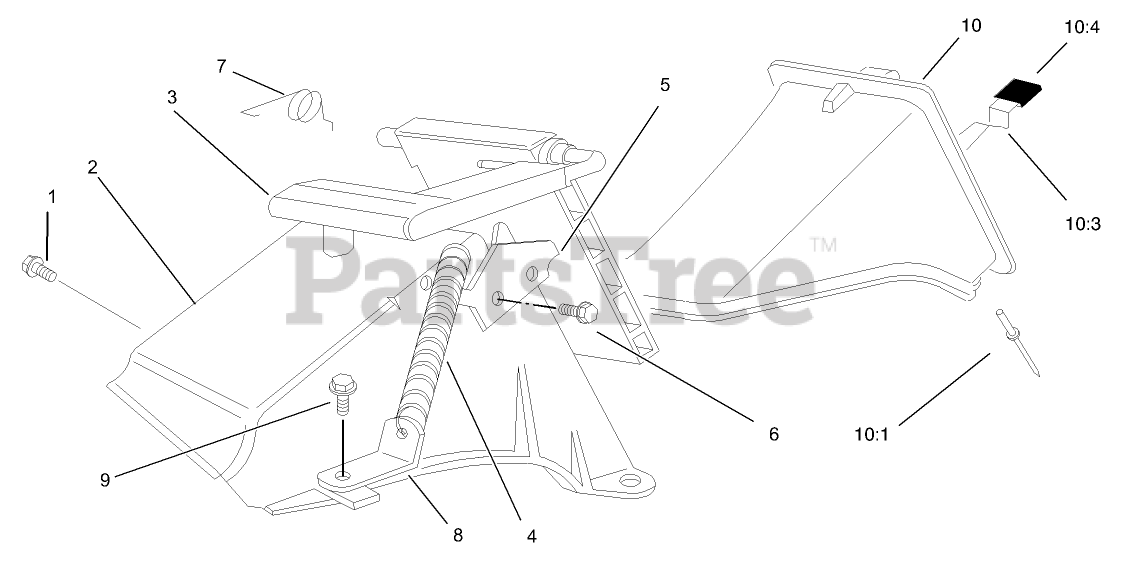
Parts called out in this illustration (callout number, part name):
1	SCREW AND WASHER ASM
2	TUNNEL-DISCHARGE
3	DISCHARGE DOOR ASM
4	SPRING-DOOR
5	LATCH-PLATE
5	PLATE-LATCH
6	SCREW-PLASTITE
7	RETAINER-DOOR
8	BRACKET-SPRING
9	SCREW-HWH
10	DISCHARGE PLUG ASM
10:1	RIVET-HEAD, FLAT
10:3	LATCH-PLUG, DISCHARGE
10:4	GRIP-LATCH
